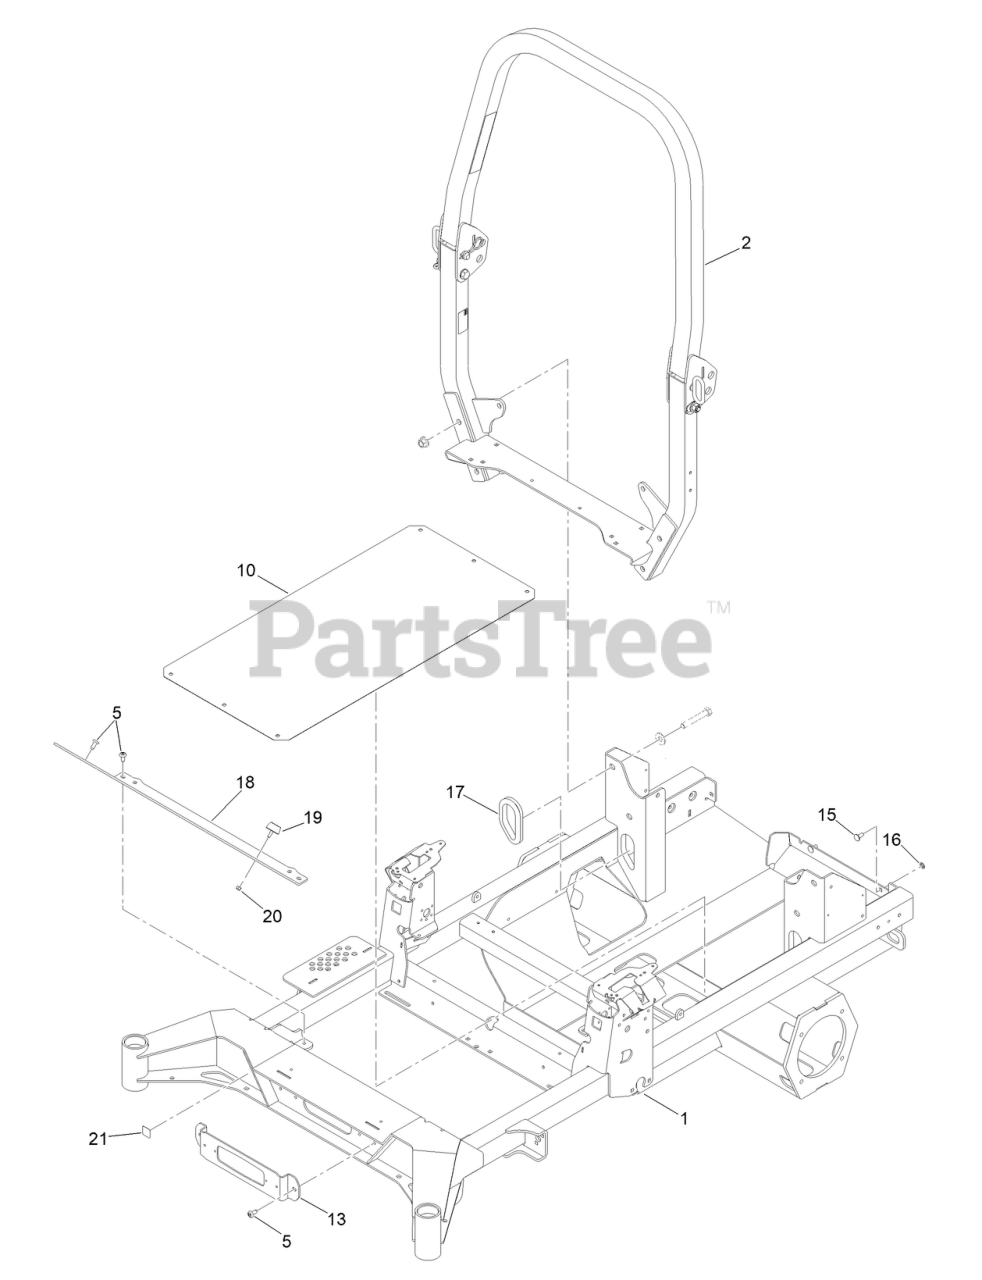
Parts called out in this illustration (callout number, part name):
2	ROPS ASM
10	PLATE-SKID
13	BRACKET-LIGHT
15	SCREW-CARR
16	NUT-PUSH
17	GROMMET-RUBBER
18	TOEBOARD [RED]
19	BUMPER
20	NUT-LOCK, NI
21	DECAL-LIGHT, WARNING
